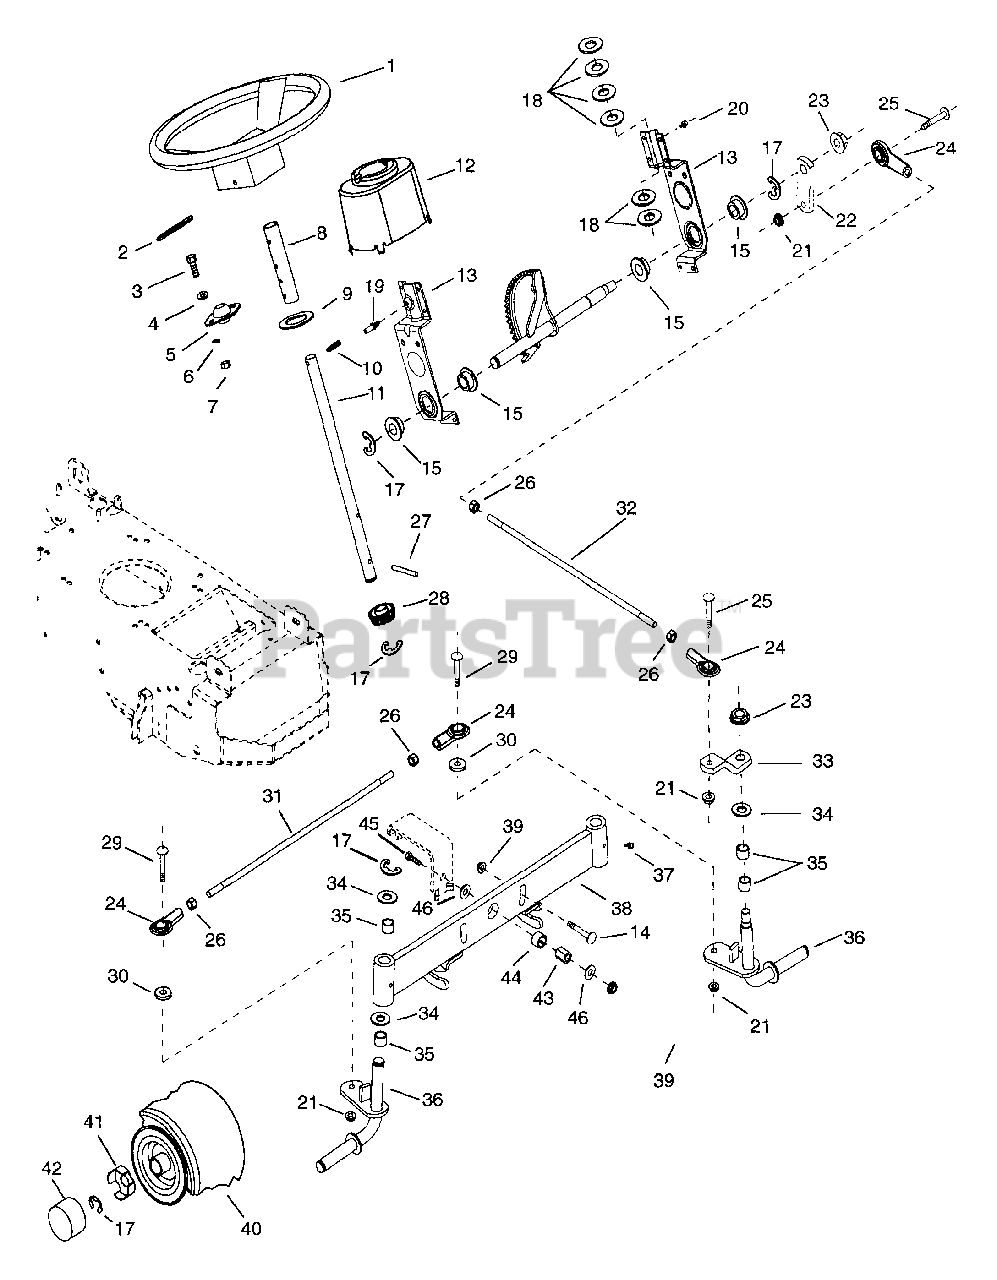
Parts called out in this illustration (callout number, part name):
1	STEERING WHEEL 13"
2	PIN-ROLL .250X1.75
3	BLT-HEX .31-18X.75 PL GR5
4	WSHR-FL-STL.312X.734X.065PL
5	BRG-FLG .751X2 HOLESX.81
6	WSHR-LK .312X.097 PL HVY
7	NUT-HEX .312-18
8	TUBE .754 X .999 X 5.00
9	WSHR-FL-STL .754X1.125X.062 PL
10	PIN-ROLL .250X1.000
11	COLUMN, STEERING
12	CONE- STEERING COLUMN
13	BRACKET, STEERING GEAR
14	BLT-HEX .38-16X1.25 GR5
15	BSHG-FLG .750X1.093X.625X1.375
16	GEAR, STEERING
17	RG-RTNG-EXT .750X.050
18	WSHR-FL-STL .755X1.375X.062 PL
19	FTG-LUBE .25-28X.256 YWZC
20	SCR-TAP .250-20X.37 HWH PL TR
21	NUT-LK-CTR .375-16 GR A PL
22	ARM, STEERING ROD
23	NUT-LK .563-18 GR 5
24	ROD END, .38 RH
25	BLT-BTHD .38-16X1.25 GR5
26	NUT .375-24 PL
27	PIN .249X1.125 DRIV-LOK SP
28	PINION GEAR-STEERING
29	BLT-HEX .38-16X1.75 PL GR5
30	BSHG-SLV .377X.624X.370
31	ROD - TIE
32	LINK - DRAG
33	ARM - STEERING SPINDLE
34	WSHR-FL-STL .755X1.375X.093
35	BSHG-SLV .750X.814X .750 BRZ
36	SPINDLE - L.H.
36	SPINDLE RH
37	SPIN DRIVE ZERK FITTING
38	AXLE, FRONT
39	NUT-LK-NYL .375-16 PL
40	T/WHL ASSY 15X6.00-6
40	RIM
40	BSHG .75 BORE
41	SPINDLE CUP
42	HUB CAP
43	BSHG-SLV .377X.623X.775 HEX
44	BSHG-SLV .626X1.000X.524 HEX
45	BLT-HEX .38-16X1.75 PL GR5
46	WSHR-FL-STL .390X1.500X.125
